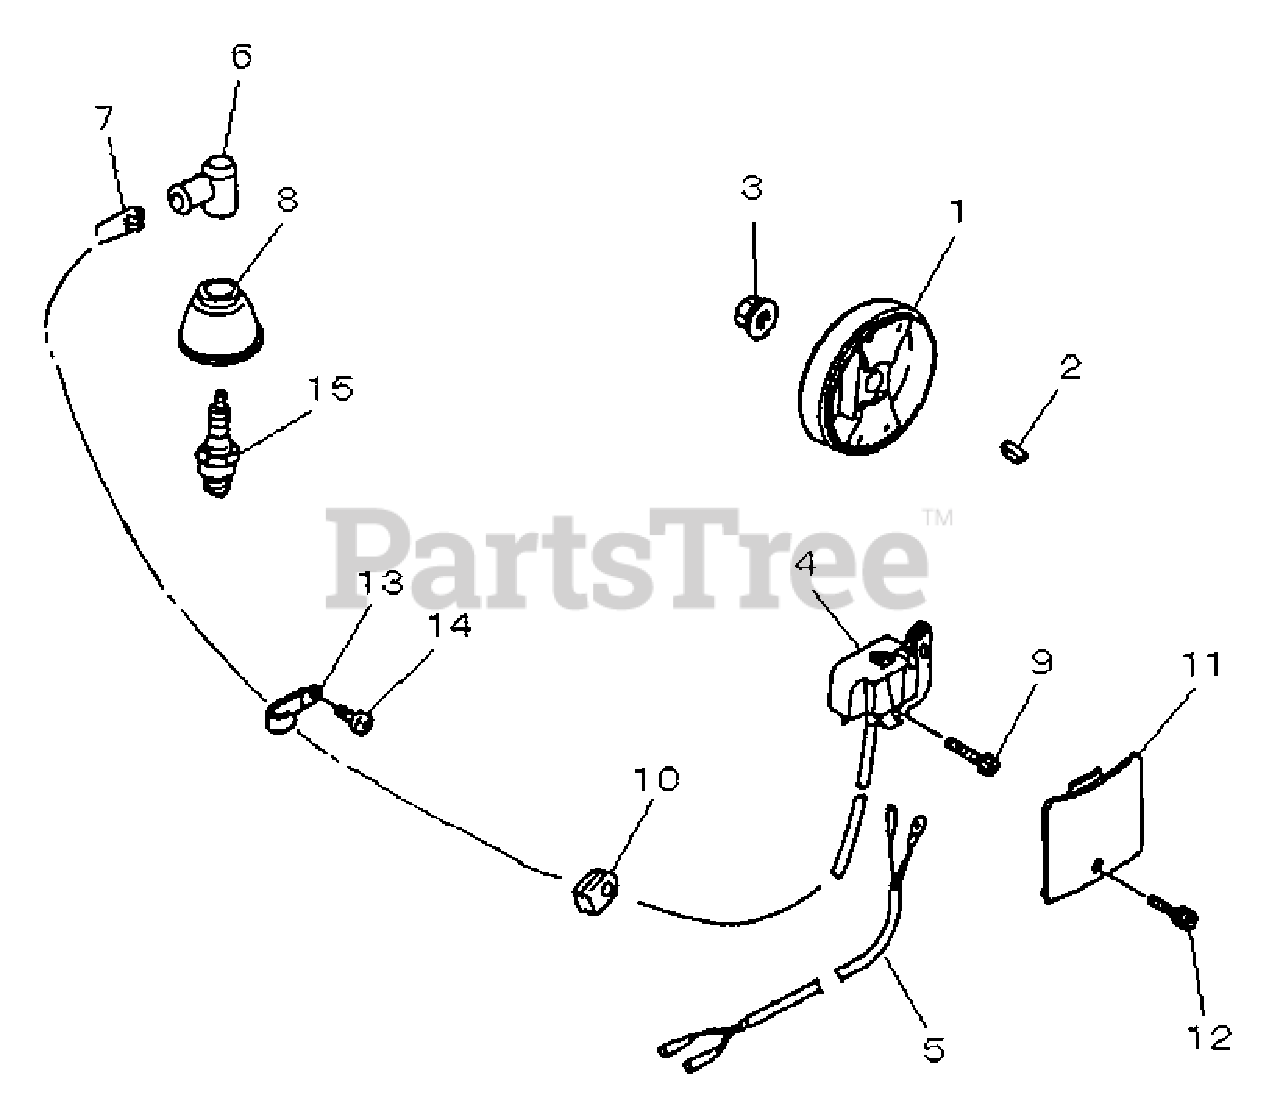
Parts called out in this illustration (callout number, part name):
1	FLYWHEEL
2	KEY
3	NUT - 10 -- FLANGE
4	COIL, IGNITION
5	LEAD ASSY
6	CAP, SPARK PLUG
7	TERMINAL, SPARK PLUG CAP
8	COVER, SPARK PLUG CAP
9	SCREW - 4X20
10	GROMMET
12	BOLT - 4X16
13	CLAMP
14	SCREW - 5X14 -- TAPPING
15	SPARK PLUG -- RCJ-6Y
